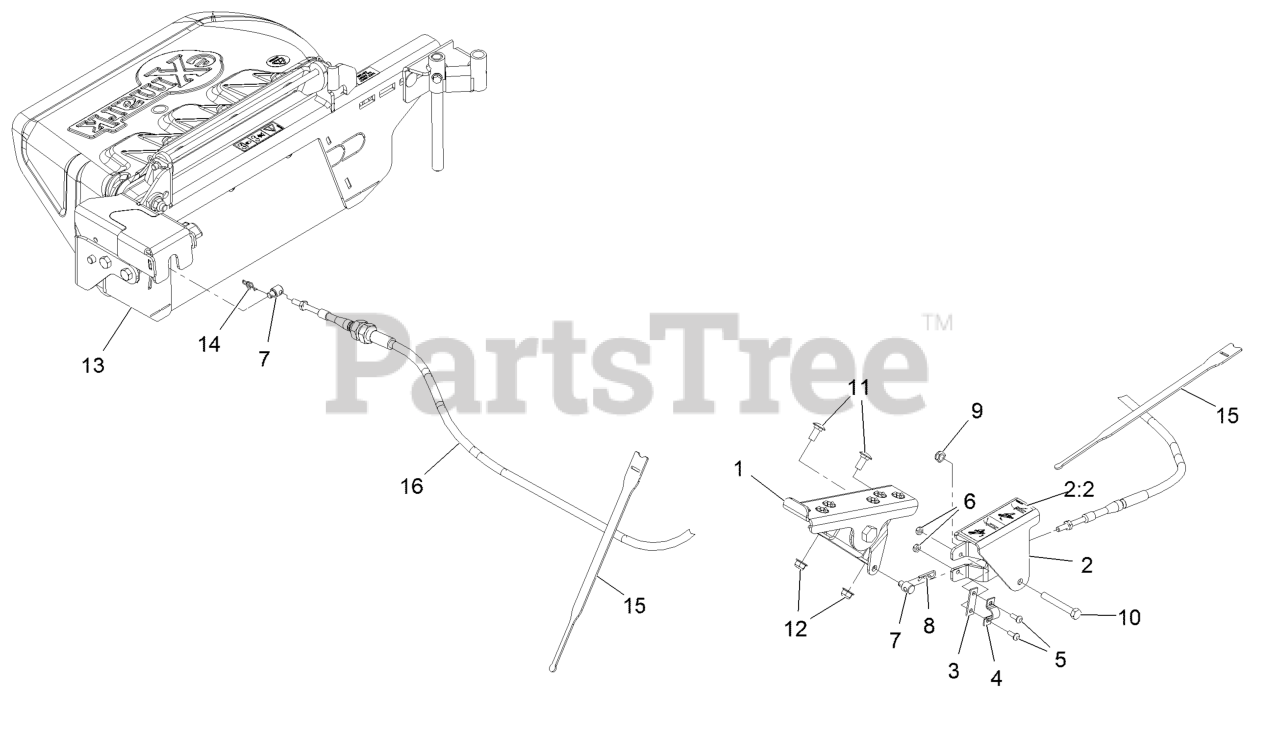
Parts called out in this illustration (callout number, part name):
1	ASM, PEDAL, OCD GATE
2	ASSEMBLY, CABLE BRACKET
2:2	DECAL-OCD OPERATION
3	SHIM,CONTROL CABLE
5	SCREW-HSBH
6	NUT-LOCK, NI
7	PIVOT, CONTROL CABLE
8	PIN-COTTER
9	NUT-LOCK, NI
10	SCREW-HH
11	SCREW-CARR
12	NUT-HF, NI
13	ASM, OCD
14	PIN-COTTER, LOCKING
15	STRAP-VELCRO, CABLE TIE
16	CABLE-DISCHARGE GATE
